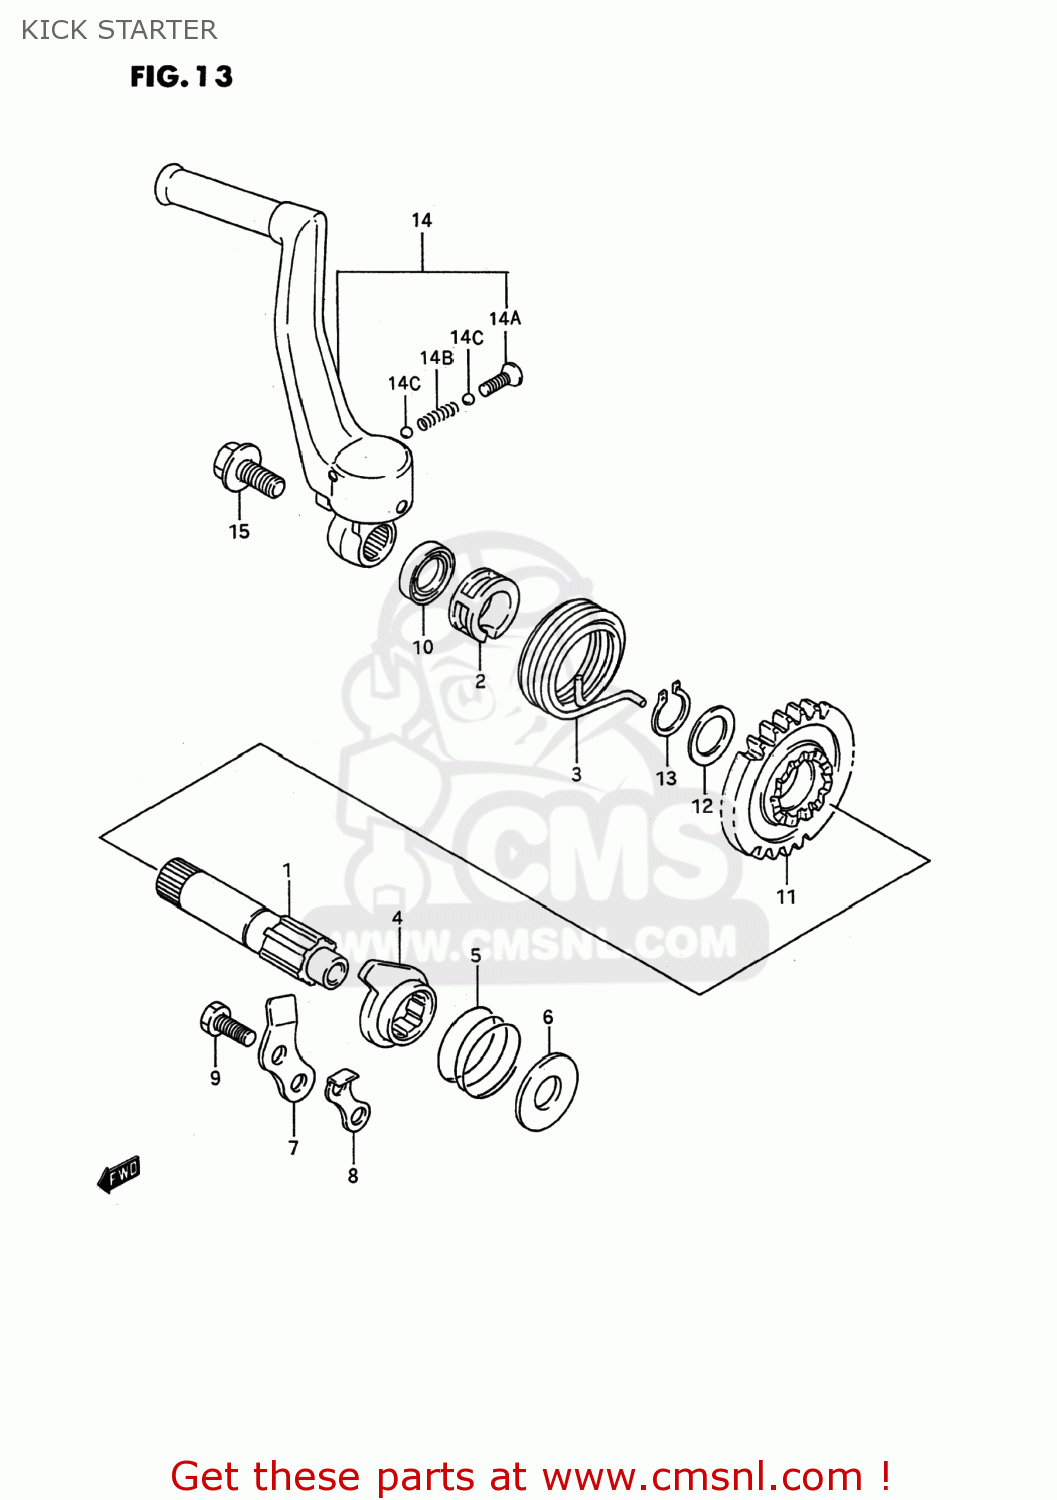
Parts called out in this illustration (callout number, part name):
1	SHAFT,KICK STARTER
2	GUIDE,KICK STARTER SFT SPRING
3	SPRING
4	STARTER,KICK
5	SPRING
6	WASHER
7	GUIDE,KICK STARTER
8	STOPPER,KICK STARTER
9	BOLT
10	SEAL,OIL(16X24X5)
11	GEAR,KICK STARTER DRIVE
12	WASHER
13	CIRCLIP 16MM
14	LEVER ASSEMBLY,KICK STARTER
15	BOLT(8X14)
